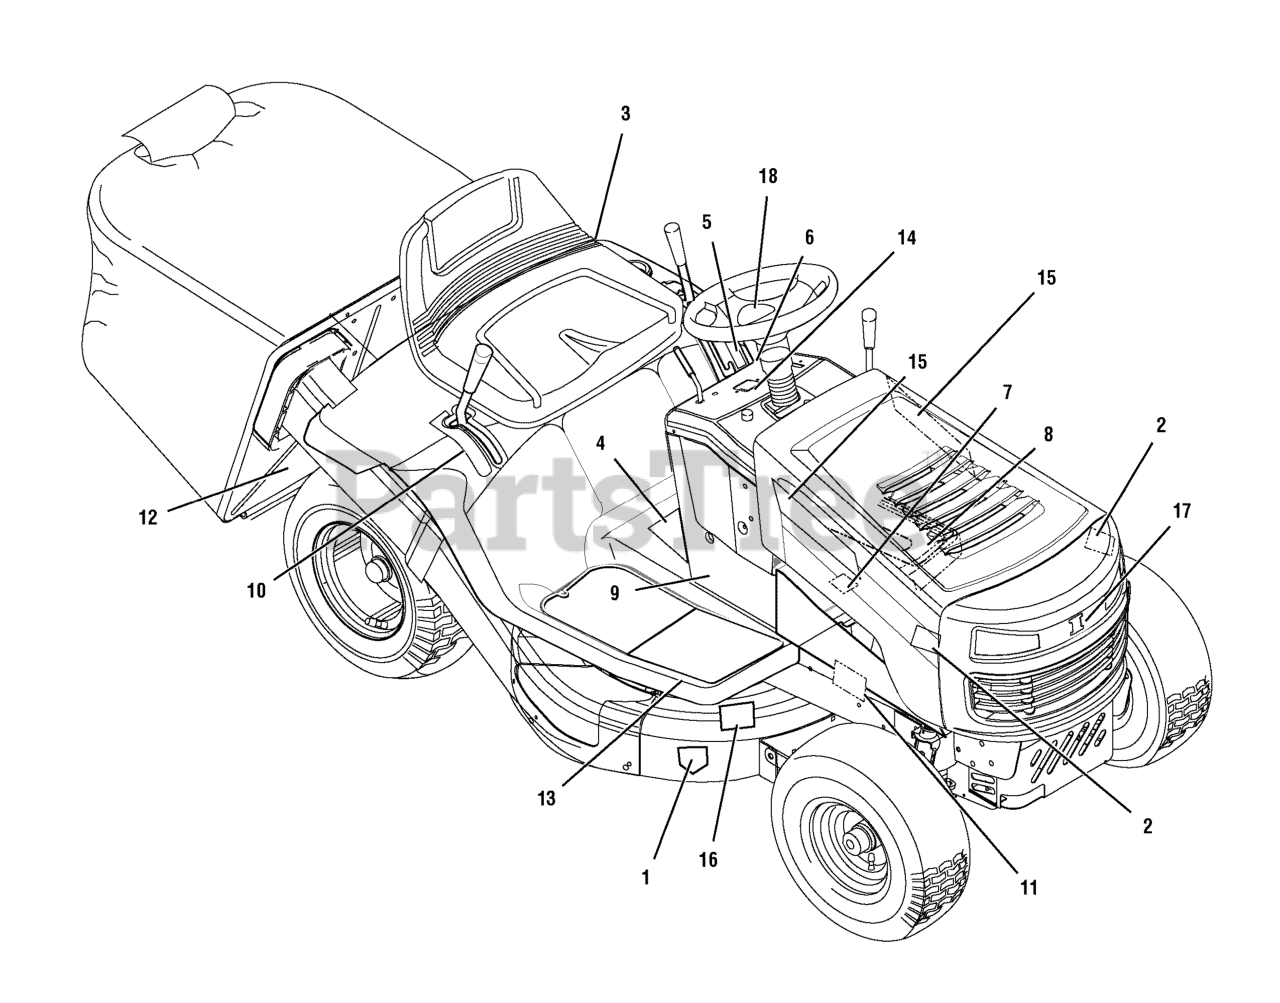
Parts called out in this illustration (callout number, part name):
1	DECAL, Cut Fingers Signal
2	DECAL, Yard King
3	DECAL, Gas
4	DECAL, Warning Export
5	DECAL, 7 Position Cut Height
6	DECAL, Deck Level
7	DECAL, DECK WIDTH 76cm
8	DECAL, Brake/Clutch Export
9	DECAL, B&S Logo
10	DECAL, 5 Speed
11	DECAL, Heat Shield Warning
12	DECAL, Warning Load Limit Export
13	DECAL, Warning Pinch Point
14	DECAL, Dash Symbols W1
15	DECAL, Yard King Logo
16	DECAL, 100db Export
17	DECAL, Yard King Front Hood
18	DECAL, Yard King Steering Wheel
